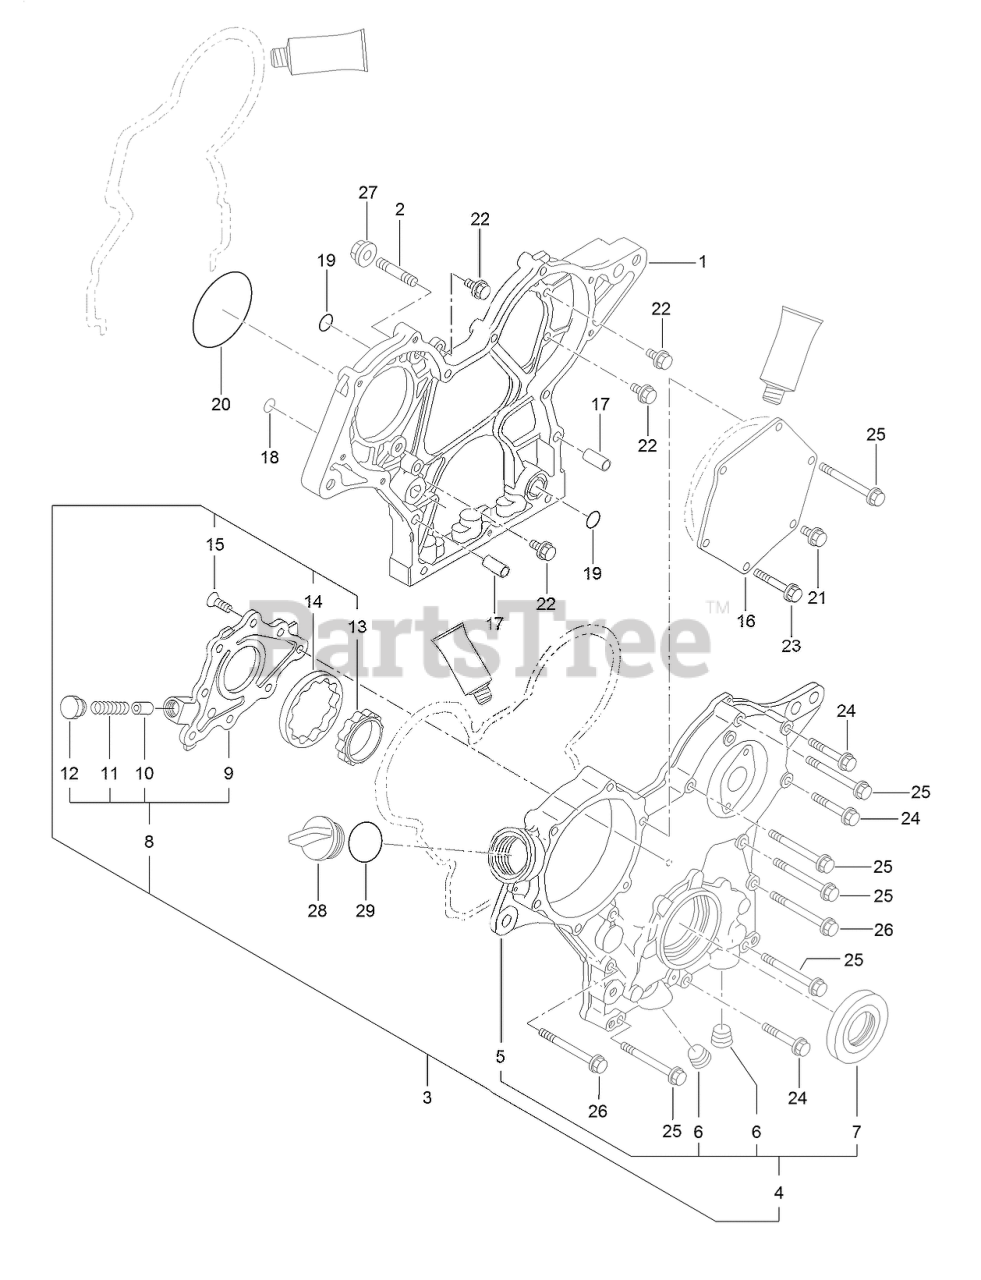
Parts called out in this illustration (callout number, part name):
1	CASE-GEAR
2	BOLT-STUD
3	COVER ASM-GEAR CASE
4	COVER ASSY-GEAR CASE
5	COVER-GEAR CASE
7	SEAL-OIL
8	COVER ASM
9	COVER-PUMP
10	VALVE-RELIEF
13	ROTOR-INNER
14	ROTOR-OUTER
16	COVER-PUMP
17	PIPE-DOWEL
28	COVER-FILLER
